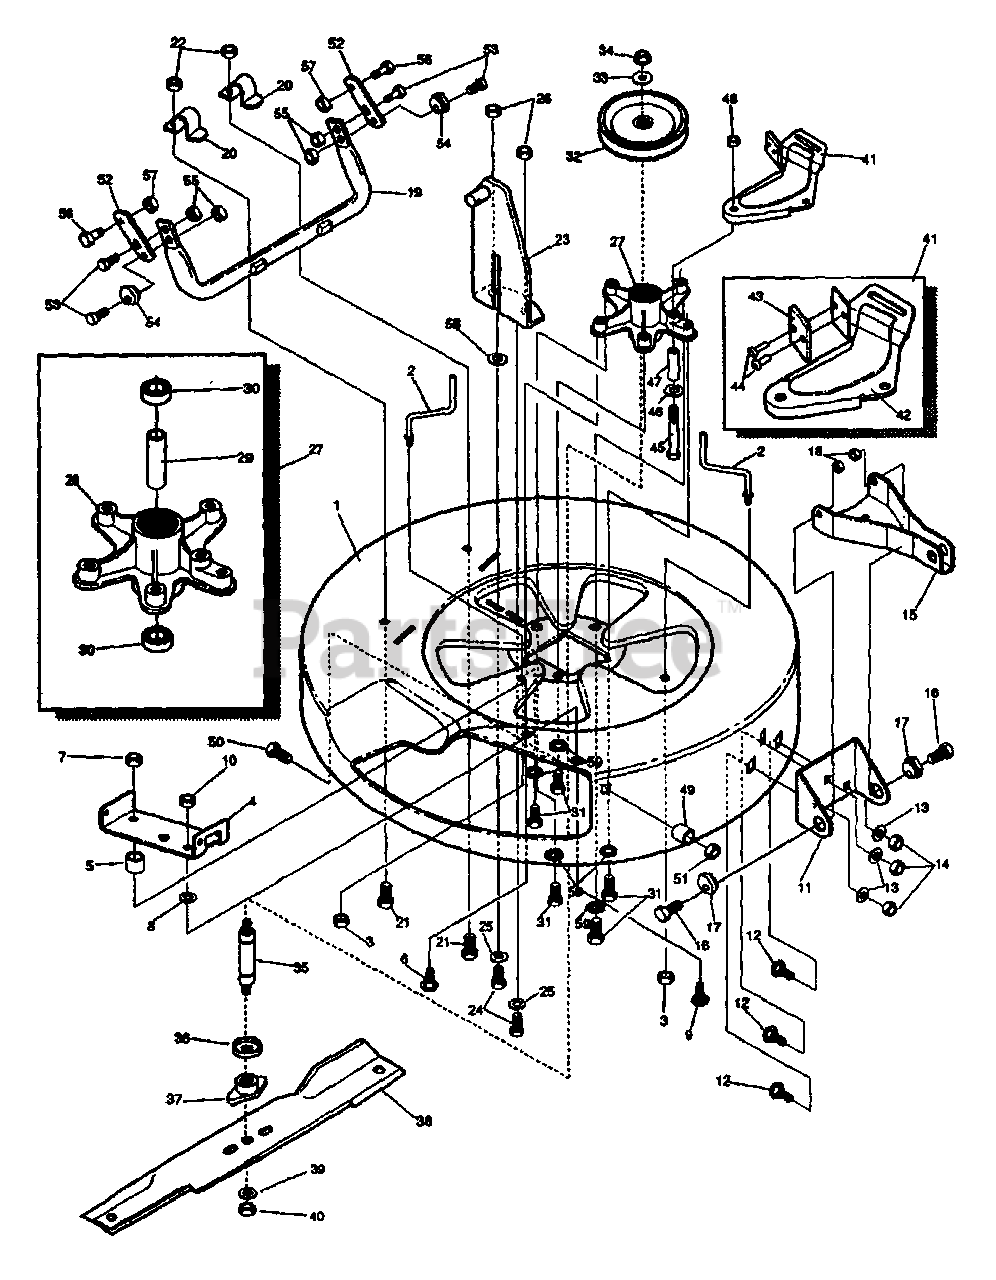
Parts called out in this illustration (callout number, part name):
1	DECK, MOWER 30 lNCH
2	GUIDE, BELT 5/18-18 THD
3	NUT, 5/16-18 REG HEX CTR LK
4	BRACKET CHUTE MOUNT
5	SPACER..344 X 1.00 X .500
6	BOLT, 5/16-18 X 1.25 CARR
7	NUT, 5/16-18 REG HEX CTR LK
8	WASHER, FLAT .333 X .87 X.119 Z
9	BOLT, 5/16-18 X .75 CARR GR2 Z
10	NUT, 5/16-18 REG HEX CTR LK
11	BRACKET, MOUNTING, FRONT
12	BOLT, 5/16-18 X .63 CARR
13	WASHER, FLAT .344 X .69 X .065
14	NUT, 5/16-18 REG HEX CTR LK
15	BRACKET, BAR, TOW, FRONT
16	SCREW, 5/16-18 X 1.00 HHC
17	ADJUSTING NUT
18	NUT, 5/16-18 REG HEX CTR LK
19	ASSY., TUBE, PIVOT
20	SUPPORT,PIVOT TUBE
21	SCREW, 5/16-18 X .75 HHC
22	NUT, 5/16-18 REG HEX CTR LK
23	ASSY LIFT BRKT
24	SCREW, 5/16-18 X .75 HHC GR5 Z
25	WASHER, FLAT .344 X .69 X .065
26	NUT, 5/16-18 REG HEX CTR LK
27	ASSEMBLY, QUILL
28	QUILL, MACHINED CASTING
29	TUBE, SPACER
30	BEARING, BALL 6204-2RS-Q
31	SCREW, 5/16-18 X .88 WA HH TAP
32	PULLEY ASSEMBLY
33	WASHER, FLAT .515 X 1.38 X .119 PL
34	NUT, 1/2-13 REG HX CTR LK
35	SHAFT, QUILL 30" MOWER
36	SHIELD, DUST, BEARING
37	HUB. BLADE ADAPTOR
38	BLADE, 30" TD MOWER 1.4 WING
39	WASHER, FLAT .515 X 1.88 X .119 PL
40	NUT, 1/2-13 REG HX CTR LK
41	BRACKET, IDLER ASSEMBLY
42	BRACKET, ARM, IDLER
43	BRAKE PAD - HARD - 232AF
44	RIVET, OVSET .187 DIA X .50 LG
45	SCREW, 5/16-18 X 2.50 HHC
46	WASHER, FLAT .333 X .87 X.119
47	SPACER, .322 X .625 X 1.810
48	NUT, 5/16-18 HWD FL CTR LK
50	BOLT, 5/16-18 X .75 CARR
51	NUT, 5/16-18 REG HEX CTR LK
52	BRACKET, BAR, REAR STABILI
53	SCREW, 5/16-18 X 1.00 HHC
54	ADJUSTING NUT
55	NUT, 5/16-18 REG HEX CTR LK
56	BOLT, .500 X .437 HHSH 3/8-16
57	NUT, 3/8-16 REG HX CTR LK
58	WASHER, FLAT .833 X .87 X 119 Z
59	WASHER, EXLK .320 X .61 X .03
